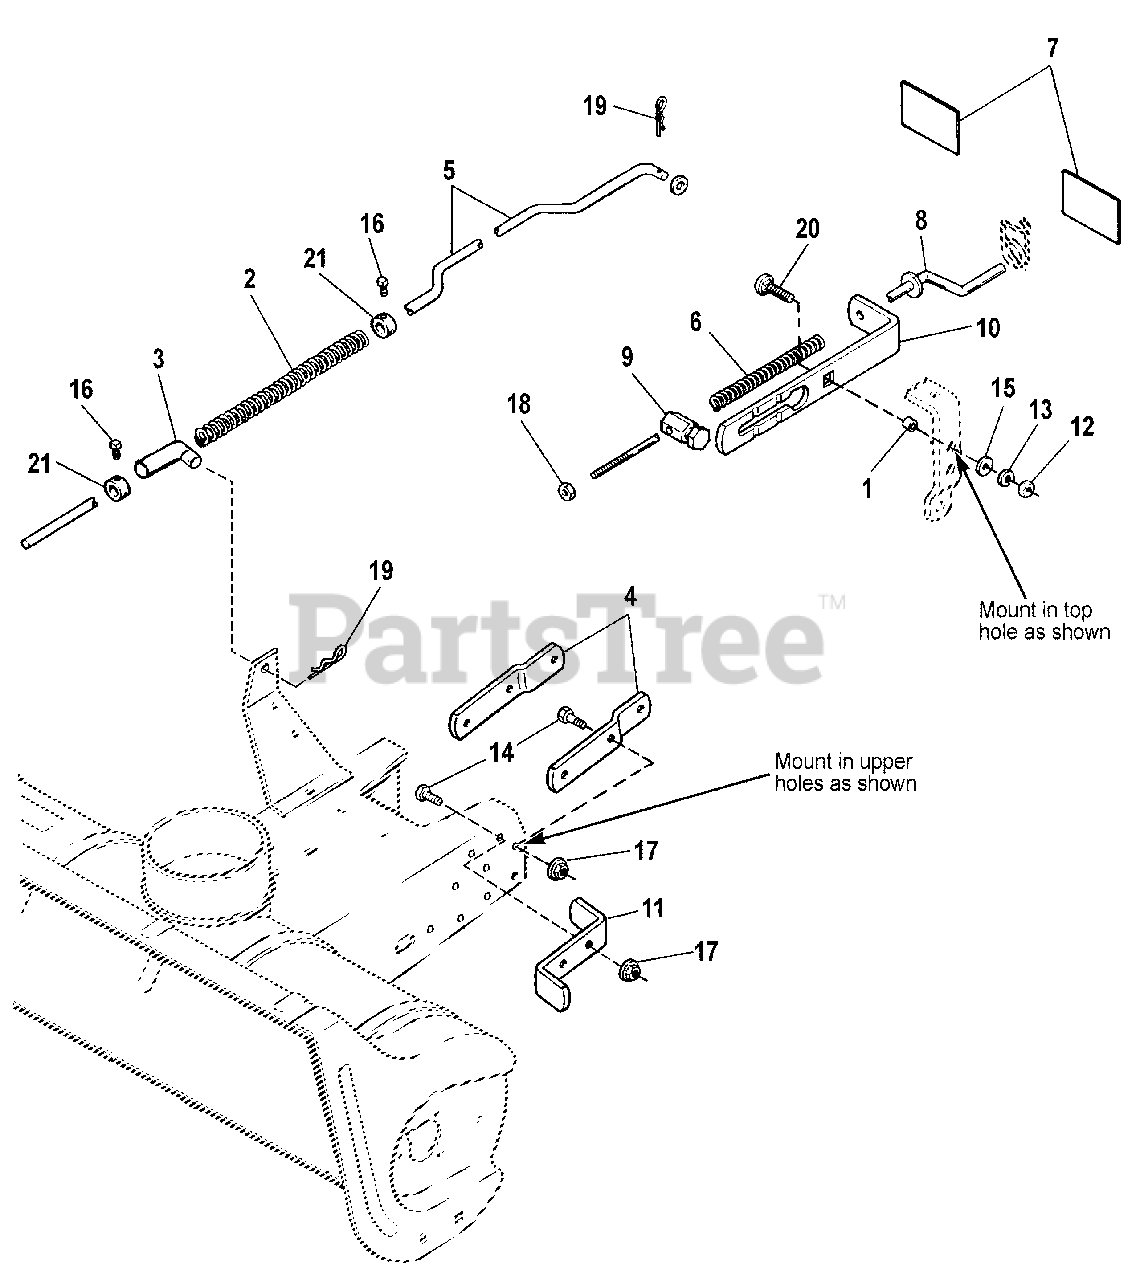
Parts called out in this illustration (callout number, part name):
2	SPRING, Compression
3	GUIDE ASSEMBLY, Rod
4	CLIP, Frame
5	ROD, Lift
6	SPRING, Compression
7	REFLECTOR, Rear Red 1-3/8 x 3
8	ROD & WASHER ASSEMBLY, Adjustment
10	GUIDE ASSEMBLY, Spring
11	BRACKET, Stop
12	NUT, Hex 3/8-16
13	LOCKWASHER, Spring 3/8
14	CAPSCREW, Hex Head, 7/16-14 X 1
15	WASHER, 5/16
16	SCREW, Set 5/16-18 x 1/2 G8
17	NUT-HEX FLANGE 7/16-1
18	NUT, Hex Centerlock, 3/8-16
19	CLIP, Hair Pin
20	CARRIAGE BOLT, 3/8-16 x 1-1/4 G5
21	COLLAR, Set
